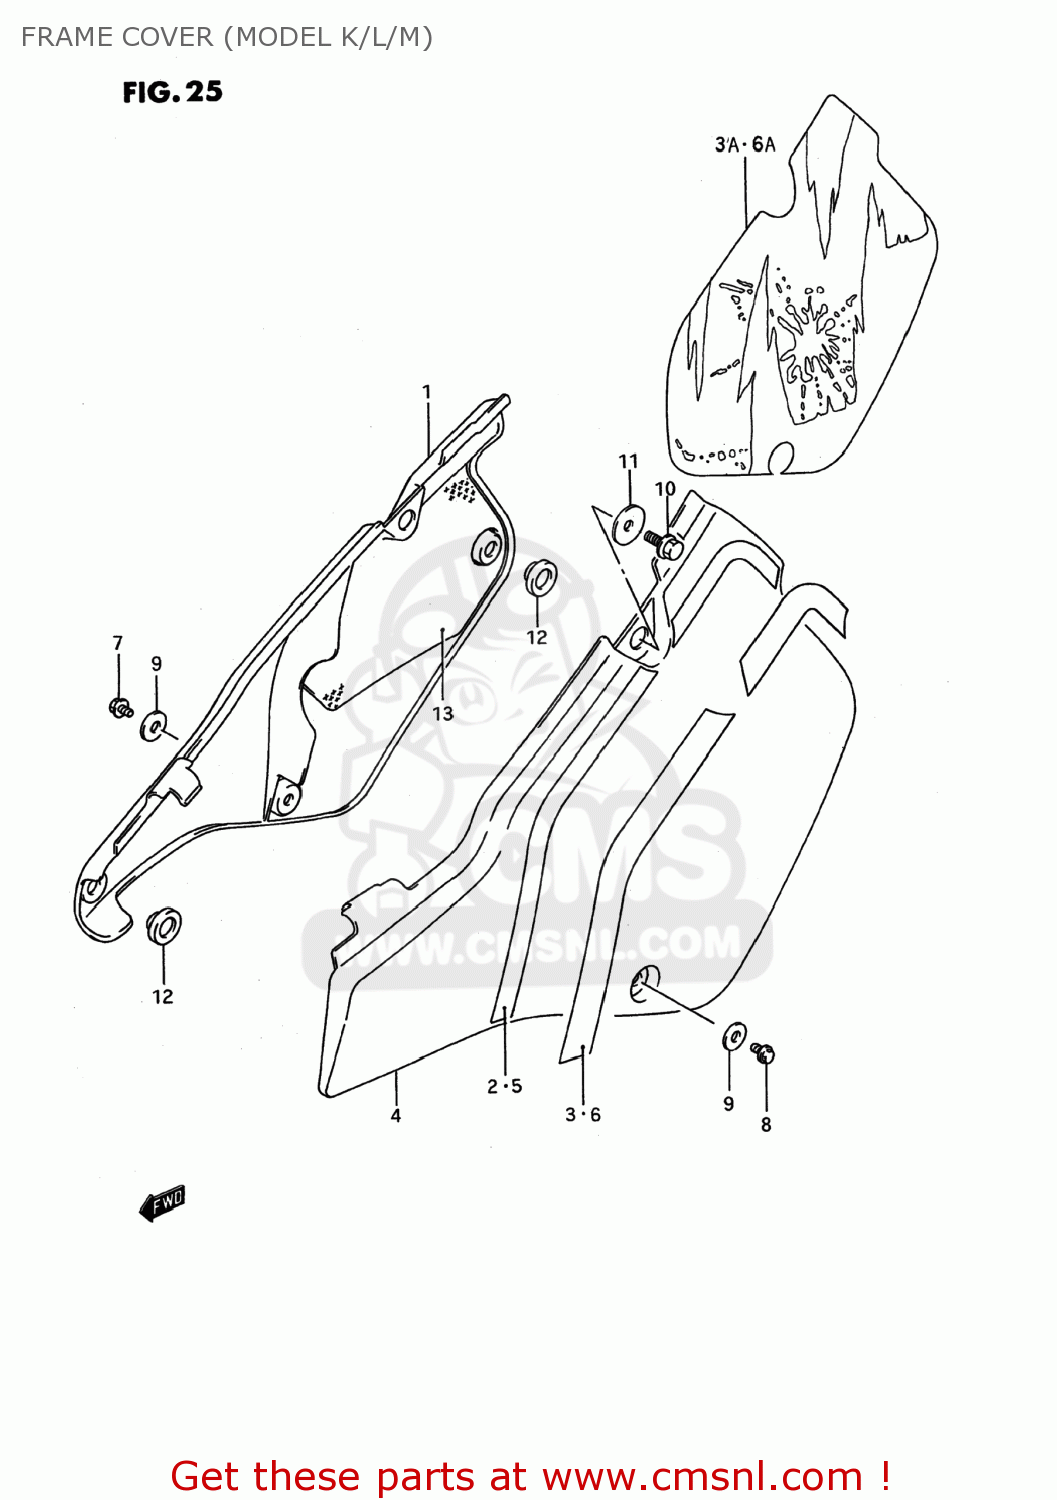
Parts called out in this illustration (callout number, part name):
1	COVER,FRAME,R(YELLOW)
2	TAPE SET,FRAME COVER S
3	TAPE SET,FRAME COVER
3A	TAPE,FRAME COVER,RIGHT
4	COVER,FRAME,L(YELLOW)
5	TAPE SET,FRAME,LEFT
6	TAPE SET,FRAME COVER
6A	TAPE,FRAME COVER,LEFT
7	BOLT
8	BOLT
9	GASKET(6.5X20X1.5) (NAS)
10	BOLT
11	WASHER
12	CUSHION
13	HEATSHIELD,FRAME COVER,R
